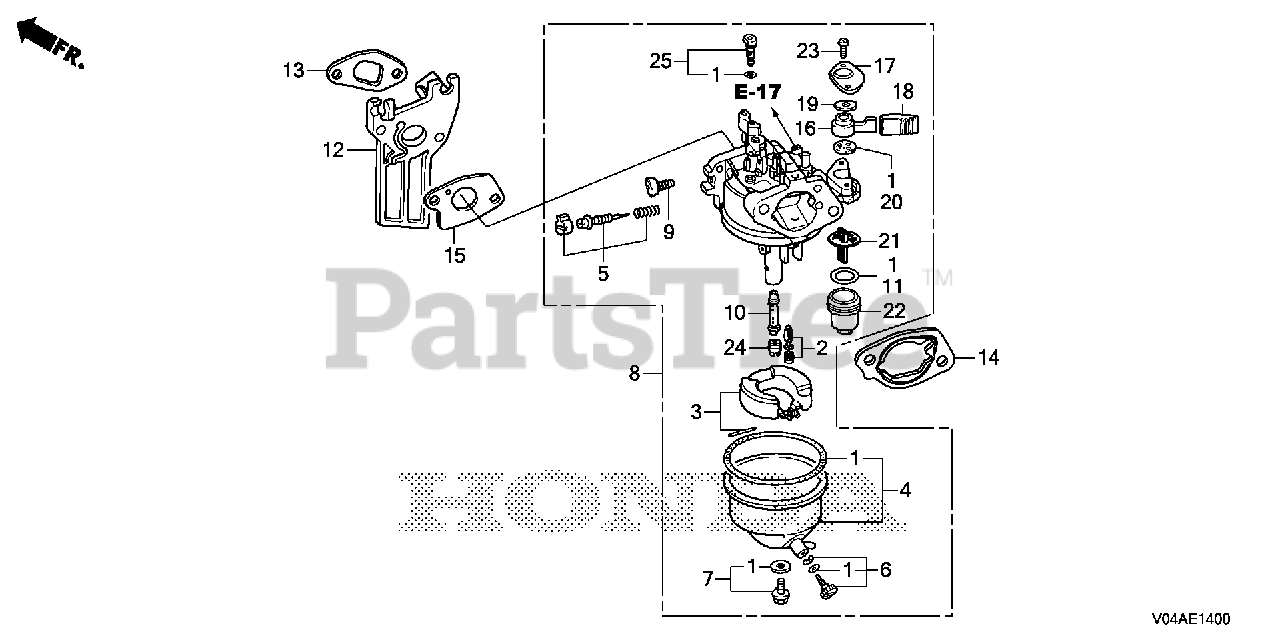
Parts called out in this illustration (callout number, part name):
1	GASKET SET
2	VALVE SET, FLOAT (SEAT NOT INCLUDED)
4	CHAMBER, FLOAT
5	SCREW SET, PILOT
6	SCREW SET, DRAIN
8	CARBURETOR ASSY. (BEA3D A)
9	SCREW, THROTTLE STOP
10	NOZZLE, MAIN
11	GASKET, FUEL STRAINER CUP
12	INSULATOR, CARBURETOR
13	GASKET, INSULATOR
14	SPACER, CARBURETOR
15	GASKET, CARBURETOR
16	LEVER, PETCOCK
17	PLATE, LEVER SETTING
18	CAP, LEVER
19	SPRING, PETCOCK LEVER
20	GASKET, PETCOCK
21	FILTER, CUP
22	CUP, FUEL STRAINER
23	SCREW, PAN (3X6)
24	JET, MAIN (#72)
24	JET, MAIN (#75)
24	JET, MAIN (#70)
25	JET SET, PILOT (#45)
